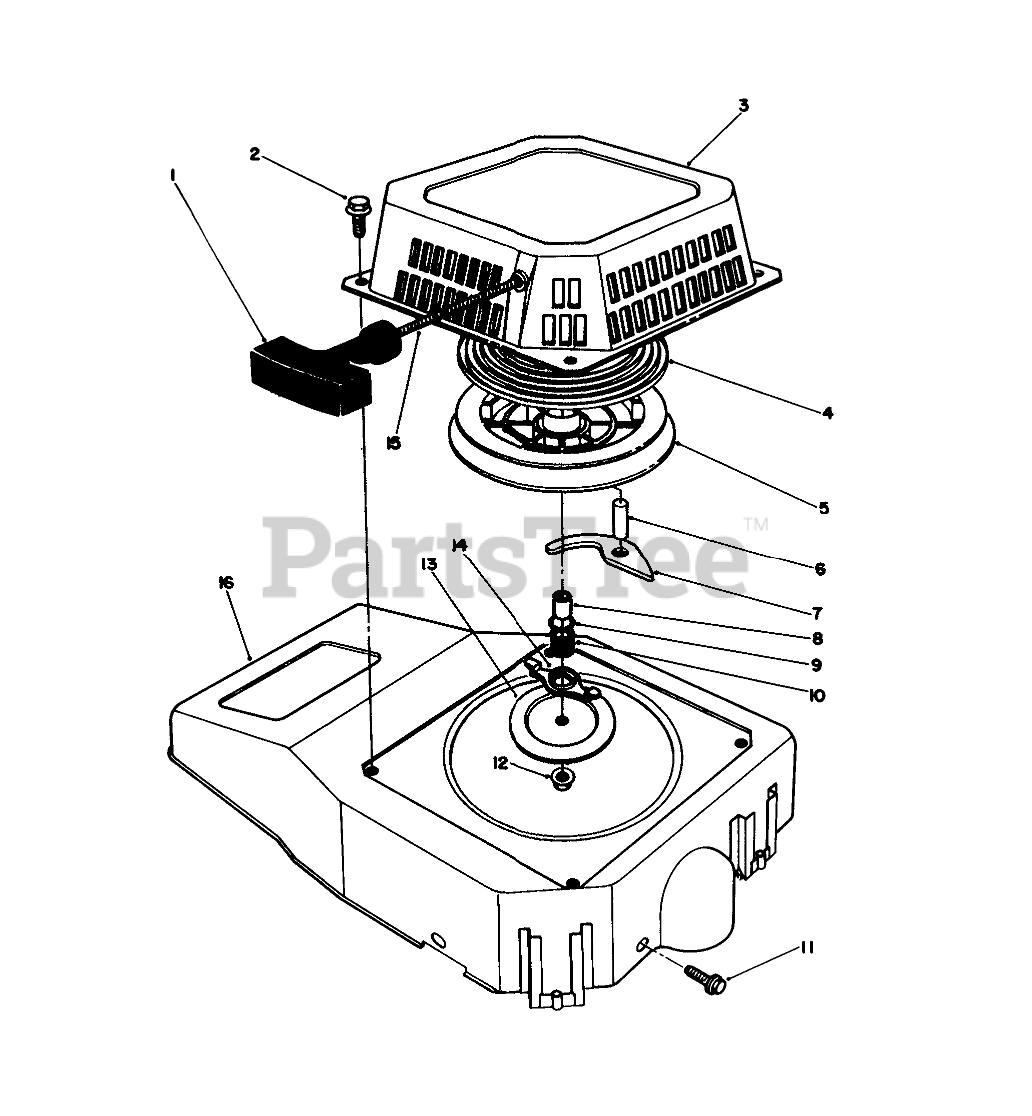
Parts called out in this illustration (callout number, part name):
1	HANDLE
2	SCREW-HHF
3	Recoil Starter Assembly (Incl. Ref. #1, & 4-15)
4	SPRING
8	Spacer
9	WASHER
10	Spring-Friction
13	PLATE
14	Guide-Paw
15	ROPE-STARTER
16	SHROUD
